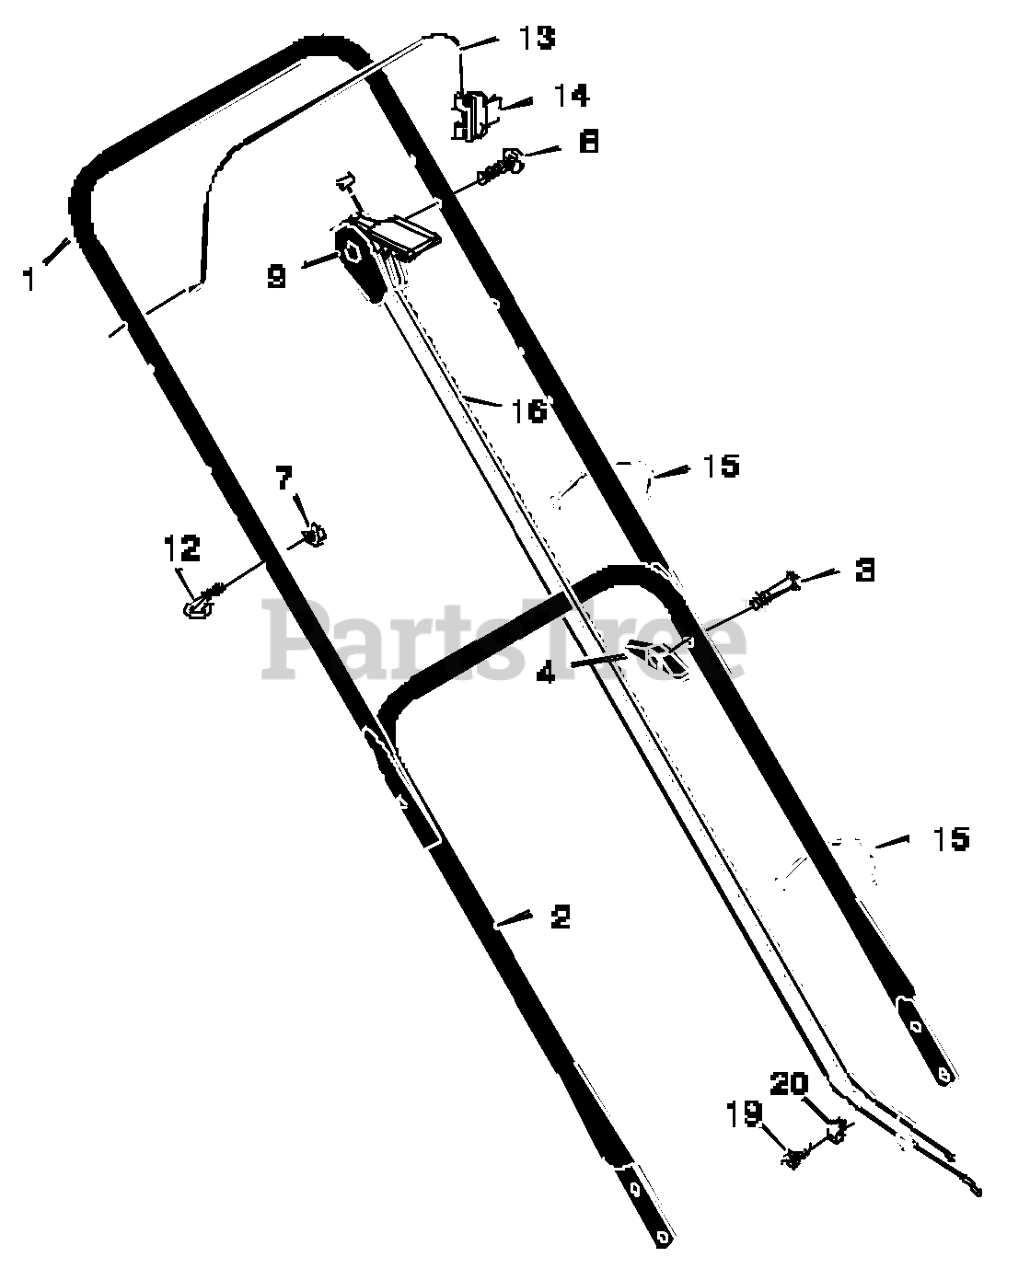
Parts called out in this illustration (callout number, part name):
1	Handle, Upper (Black)
2	Handle, Lower (Black)
4	Knob, Plastic
7	Locknut
9	Throttle Control
12	GUIDE, ROPE
13	Engine Stop Lever
14	Bracket, Stop Lever
15	Fastener, Cable
16	Engine Stop Cable
